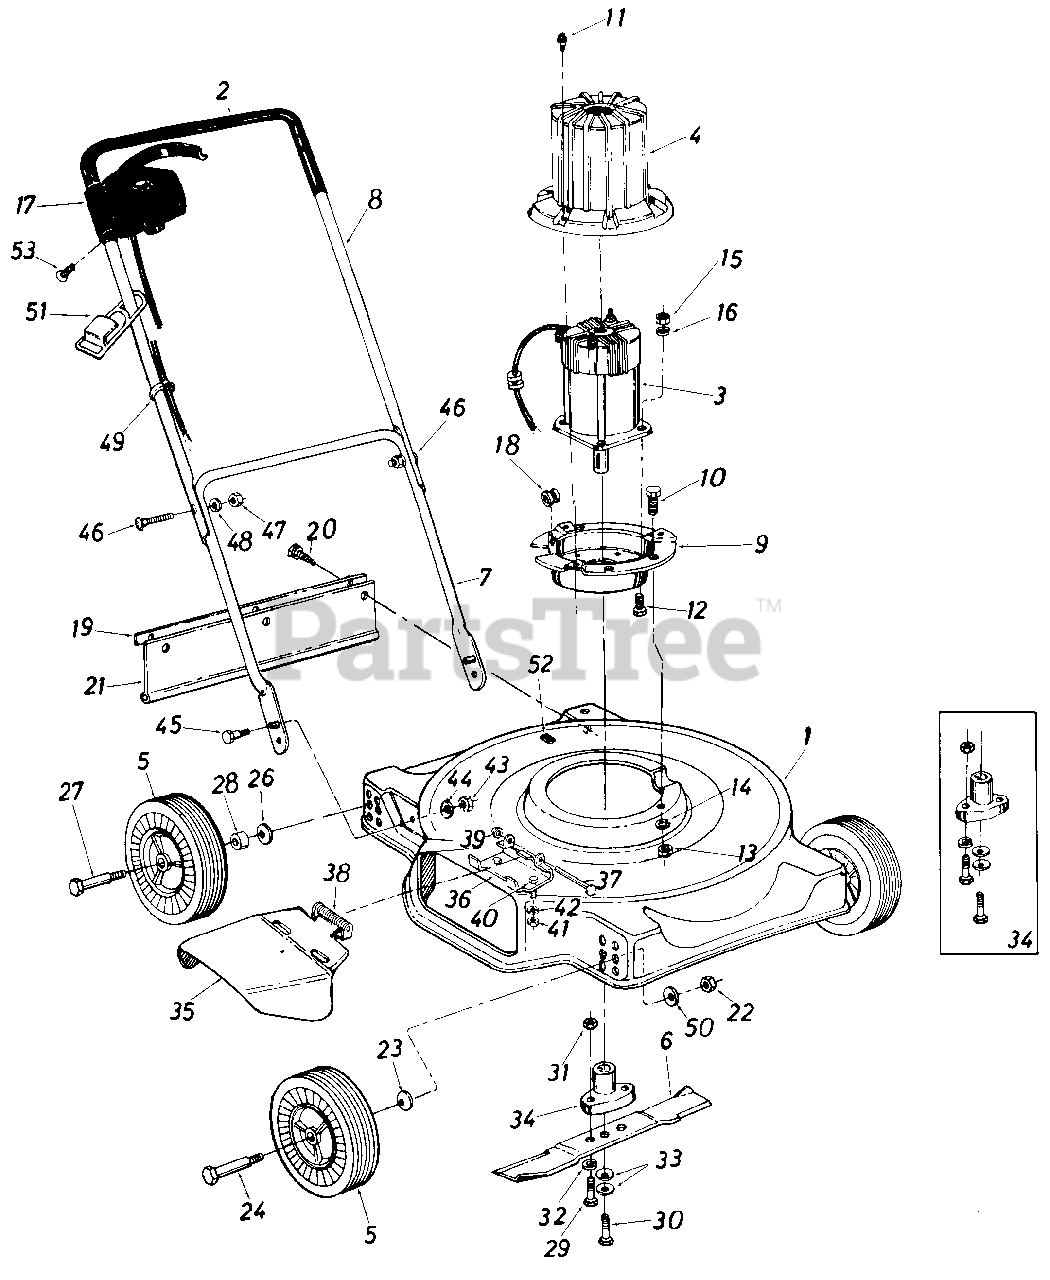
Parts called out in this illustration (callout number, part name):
1	20" Deck Ass'y.
4	Motor Shroud
5	Wheel Ass'y. Comp. 7 x 1.50
6	20" Blade
7	Lower Handle
8	Upper Handle
9	Drive Housing Brk't. L.H.
10	Hex Bolt 3/8-16 x 1.00" Lg.
11	Hex Wash Hd. 'F" Tap Scr. #10-32 x .314" Lg.
12	Hex Bolt 1/4-20 x 1.00" Lg.
13	Hex Nut 3/8-16 Thd.
14	L-Wash. 3/8 I.D.*
15	Hex Nut 1/4-20 Thd.
16	L-Wash. 1/4" I.D.
17	Control w/Cord
18	Cord Restraint
19	Retaining Strip
20	Hex Wash. Hd. AB-Tap Scr. 1/4 x .62" Lg.
21	Rear Flap Ass'y. 4.65 x 17.2" Lg.
22	Hex Nut 3/8-16 Thd.
23	Bell-Wash. .400" I.D. x .88" O.D.
24	Shld. Bolt .498" Dia. x 1.450" Lg.
26	Bell-Wash. .400" I.D. x .88" O.D.
27	Shld. Bolt .498" Dia. x 1.830" Lg.
28	Spacer.511" I.D. x .70" O.D. x .38" Lg.
29	Hex Bolt 5/16-24 x 1.00" Lg. Grade 5
30	Hex Bolt 5/16-24 x .75" Lg.
31	Hex Nut 5/16-24 Thd.
32	L-Wash. 5/16" I.D.
33	Bell-Wash. .345" I.D. x .88" O.D.
34	Blade Adapter Kit
35	Chute Def lector Ass'y. Comp.
36	Deflector Hinge Plate
37	Hinge Pin
38	Torsion Spring
39	Push On Flange Nut
40	Hex Bolt 1/4-20 x .50" Lg.
41	Hex Nut 1/4-20 Thd.
42	L-Wash. 1/4" I.D.
43	Hex Nut 5/16-18 Thd.
44	Bell-Wash. .345" I.D. x .88" O.D.
45	Shld. Bolt .437" Dia. x .268" Lg.
46	Curved Hd. Carr. Bolt 5/16-1 x 1.38" Lg.
47	Hex Nut 5/16-18 Thd.
48	L-Wash. 5/16" I.D.
49	Cable Tie
50	Bell-Wash. .39" I.D. x 1.13" O.D.
51	Restraint
52	Plastic Plug
53	Truss Mach. AB-Tap Scr.
